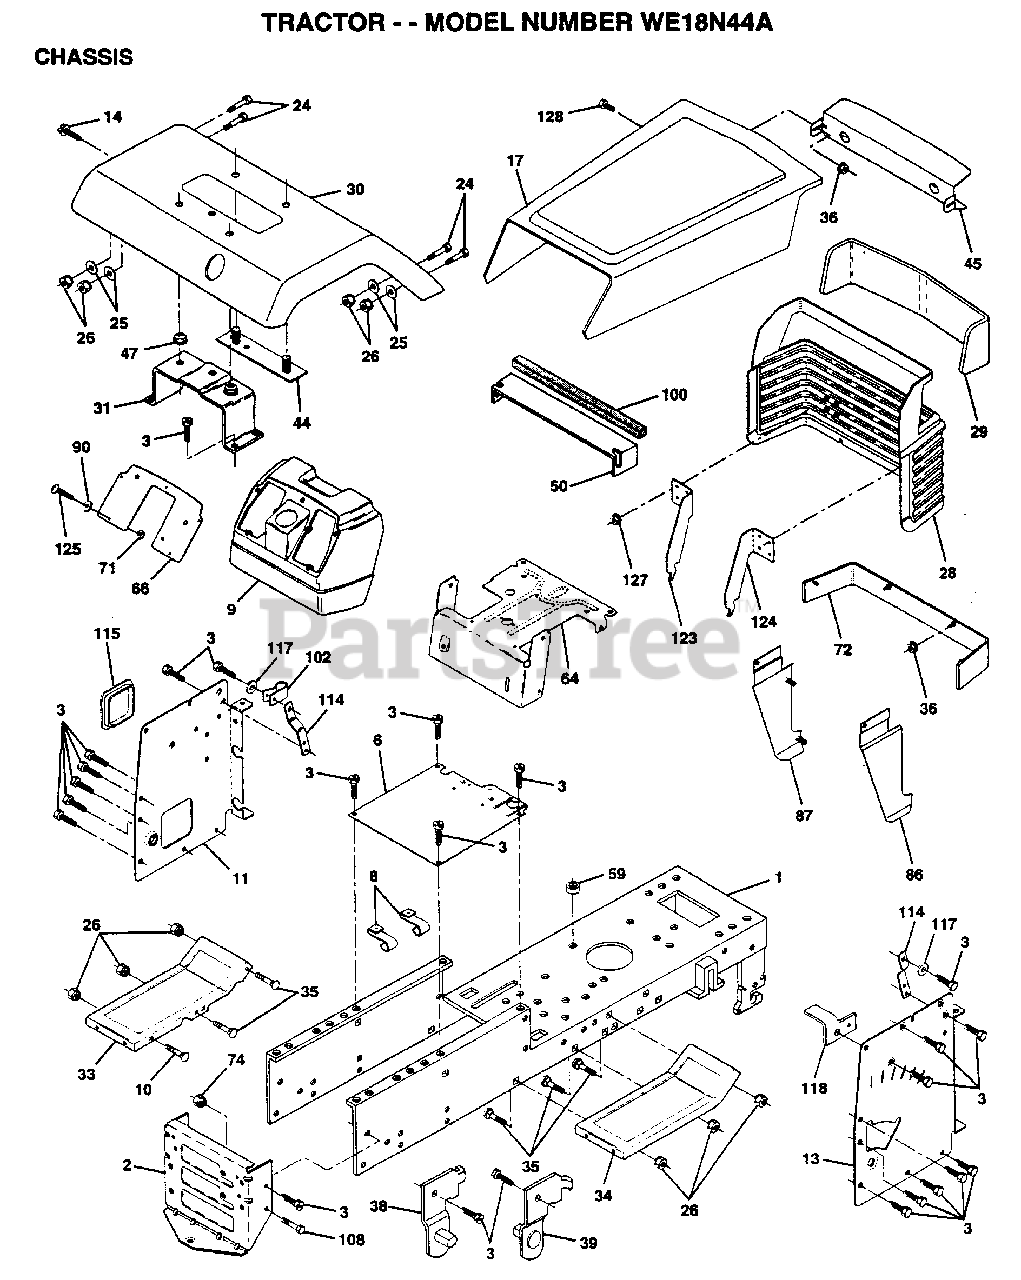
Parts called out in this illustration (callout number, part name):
1	CHASSIS.WLD.11GA
2	DRAW BAR
3	SCREW
8	"CLIP,INSULATOR"
9	DASH.PLASTIC.BLK
11	PANEL.DASH.LH.PNT
13	PANEL.DASH.RH.PNT
14	SCREW LT
17	HOOD/GRILLE ASM
24	BOLT
25	WASHER
26	NUT
28	GRILLE ASM WELD
30	FENDER PNT
31	BRKT.ASM.FENDER
33	FOOTREST.LH.LT/GT
34	FOOTREST.RH.LT/GT
35	BOLT
36	PAL NUT LT
38	BRACKET ASM LH
39	BRACKET ASM RH
44	STRAP ASM FENDER
47	NUT-PUSH YT
50	"BAFFLE,HOOD"
66	PLATE DASH SILKSC
71	NUT HXKEP 1/4X20
72	STRAP FENDER ASM
86	PANEL SIDE RH ASM
87	PANEL SIDE LH ASM
90	WASHER PM
100	FOAM STRIP T
102	"CLIP,INSULATOR"
114	BRACKET.SUPT.DASH
115	COVER ACCESS
117	WASHER.SERRATED.
118	BRACKET.CLUTCH.MC
124	BRACKET.PICK.RH
125	SCREW
127	PAL NUT
128	SCREW SPECIAL
